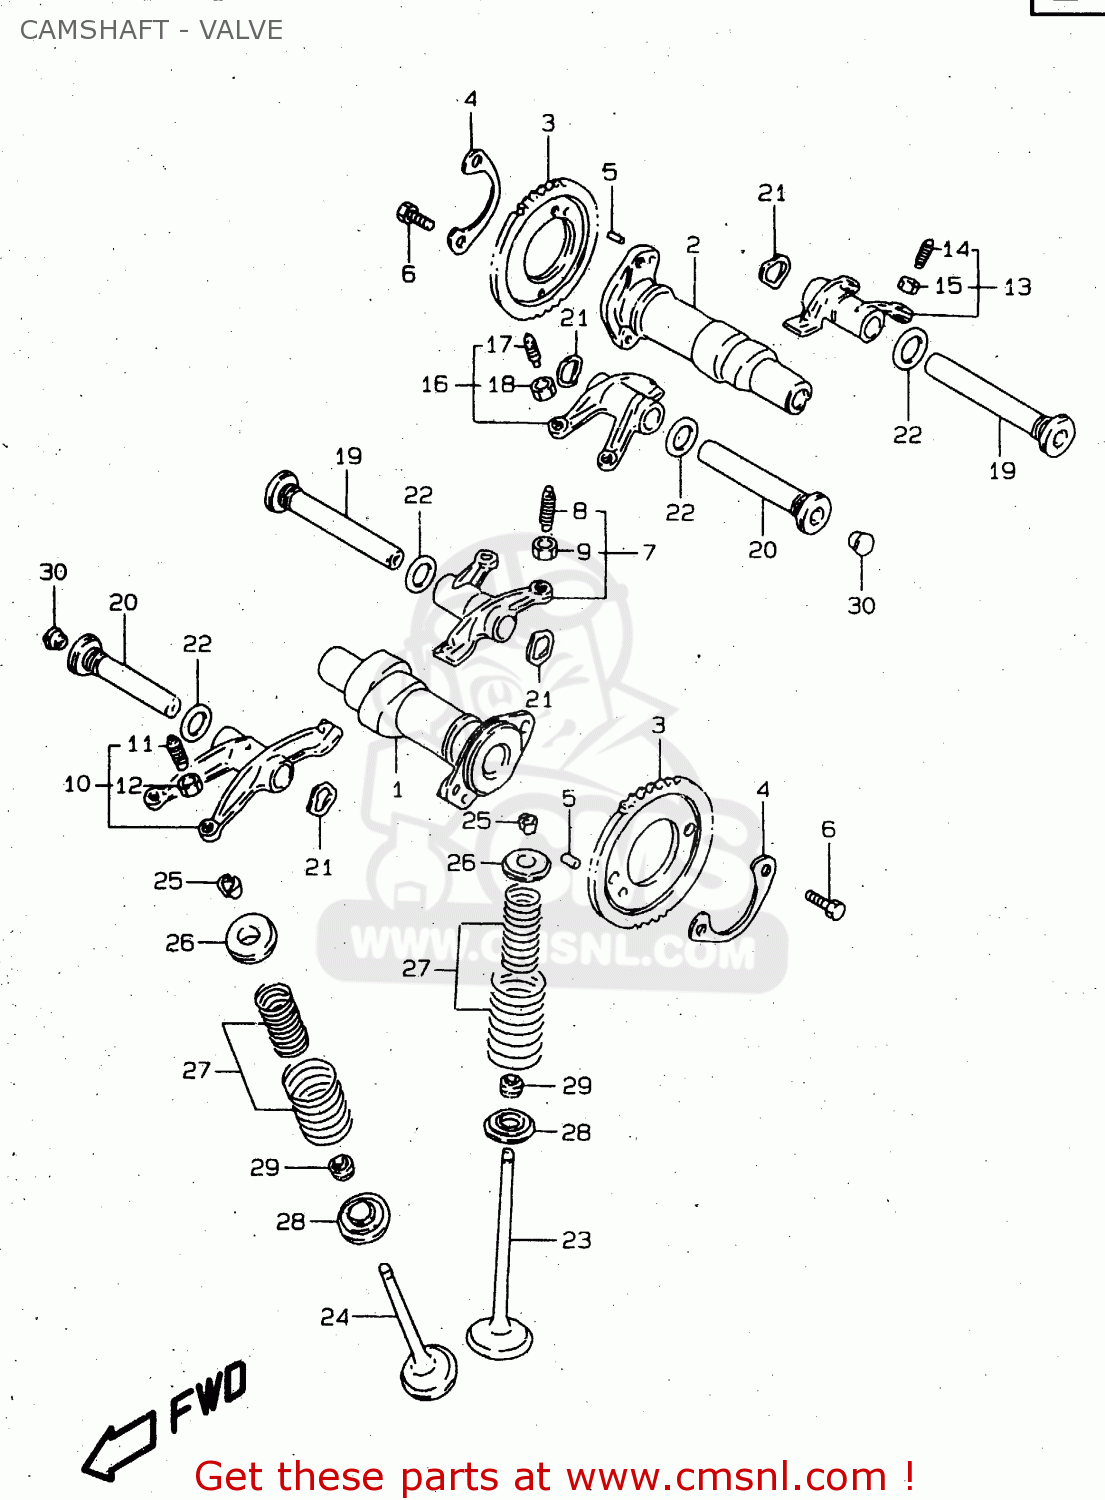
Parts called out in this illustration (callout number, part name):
1	CAMSHAFT,FR
2	CAMSHAFT,RR
3	SPROCKET,CAMSHAFT(NT:42)
4	WASHER,CAM CHAIN SPROCKET
5	PIN
6	BOLT(6X12.5)
7	ARM,INTAKE VALVE ROCKER FR
8	SCREW,TAPPET ADJUSTING
9	NUT,ADJUSTING SCREW
10	ARM,EXHAUST VALVE ROCKER FR
11	SCREW,TAPPET ADJUSTING
12	NUT,ADJUSTING SCREW
13	ARM,INTAKE VALVE ROCKER RR
14	SCREW,TAPPET ADJUSTING
15	NUT,ADJUSTING SCREW
16	ARM,EXHAUST VALVE ROCKER RR
17	SCREW,TAPPET ADJUSTING
18	NUT,ADJUSTING SCREW
19	SHAFT,INTAKE VALVE ROCKER ARM
20	SHAFT,EXHAUST VALVE ROCKER ARM
21	WASHER
22	GASKET(13.8X18.8X4.8) (NAS)
23	VALVE,INTAKE
24	VALVE,EXHAUST
25	COTTER,VALVE
26	RETAINER,VALVE SPRING
27	SPRING SET,VALVE
28	SEAT,VALVE SPRING
29	SEAL,OIL(5.5X11X8.2)
30	CAP(OD:10)
